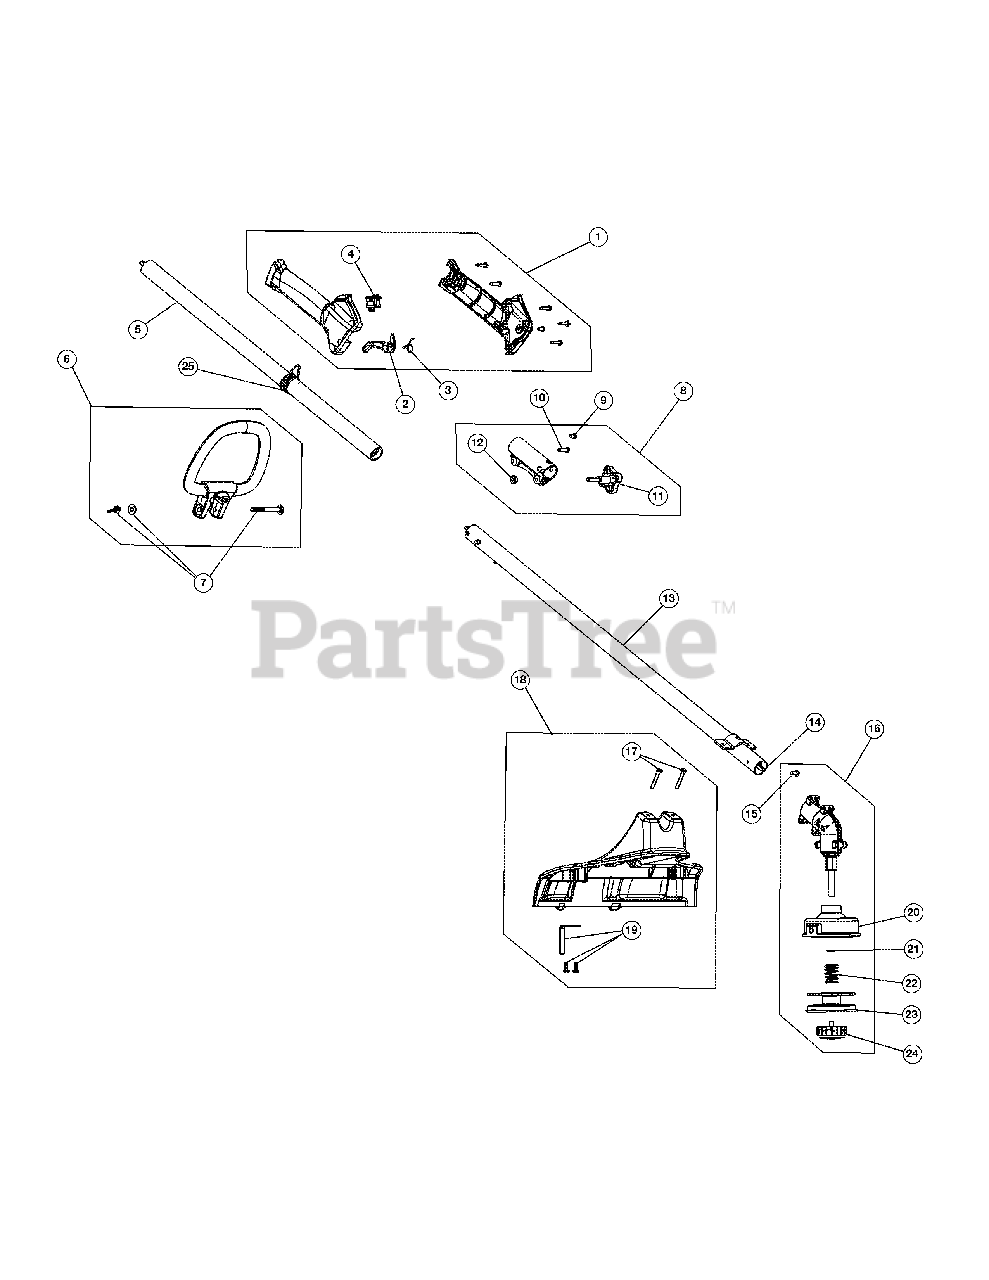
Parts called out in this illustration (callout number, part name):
1	Throttle Housing Assembly (Incl. Ref No. 2-4)
2	Throttle Trigger
3	Throttle Trigger Spring
5	Upper Drive Shaft Housing Assembly
6	D-Handle Assembly (Incl. Ref No. 7)
7	D-Handle Hardware
8	Split Boom Coupler (Incl. Ref No. 9-12)
11	Adjustment Knob (Incl. Ref No. 12)
12	Knob Retaining Nut
13	Lower Drive Shaft Housing Assembly
14	Lower Flexible Drive Shaft
15	Anti-Rotation Screw
16	Gear Box Assembly (Incl. Ref No. 15 & 20-24)
17	Shield Mounting Screws
18	Shield Assembly (Incl. Ref No. 17 & 19)
19	Blade Assembly
20	Outer Spool Assembly
21	Retainer
23	Inner Reel
24	Bump Knob Assembly
25	Shoulder Strap Clip
